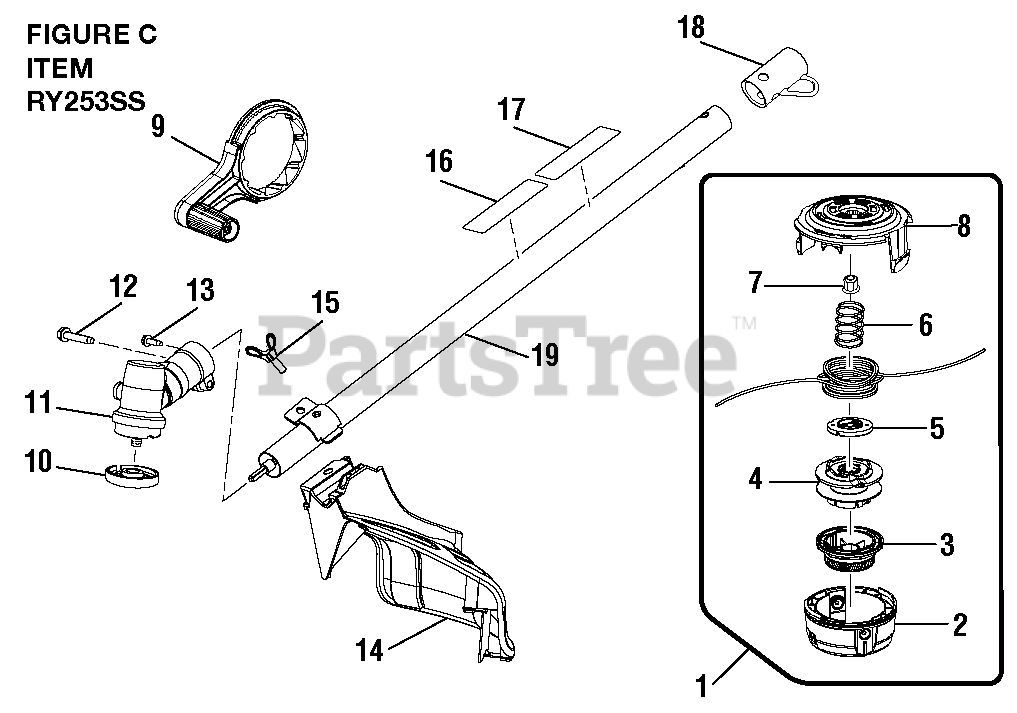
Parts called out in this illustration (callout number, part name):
1	Trimmer Head Assembly (.095)
2	Lower Housing
3	Bump Knob (Green)
5	String Guide
6	Compression Spring
7	Hex Nut (M8, L.H. Thread)
8	Upper Housing
9	Crank Handle Assembly
10	Flanged Washer
11	Gear Case Assembly
12	Screw (1/4-20 x 1-1/4 in., Hex Washer Hd. S.T.)
13	Screw (10-24 x 5/8 in., Hex Washer Hd. S.T.)
14	Grass Deflector Assembly
15	Wing Screw (1/4-20 x 7/8 in.)
16	Expand-it Label
17	Warning Icon Label
18	Storage Hanger Cap
19	Straight Shaft Assembly
